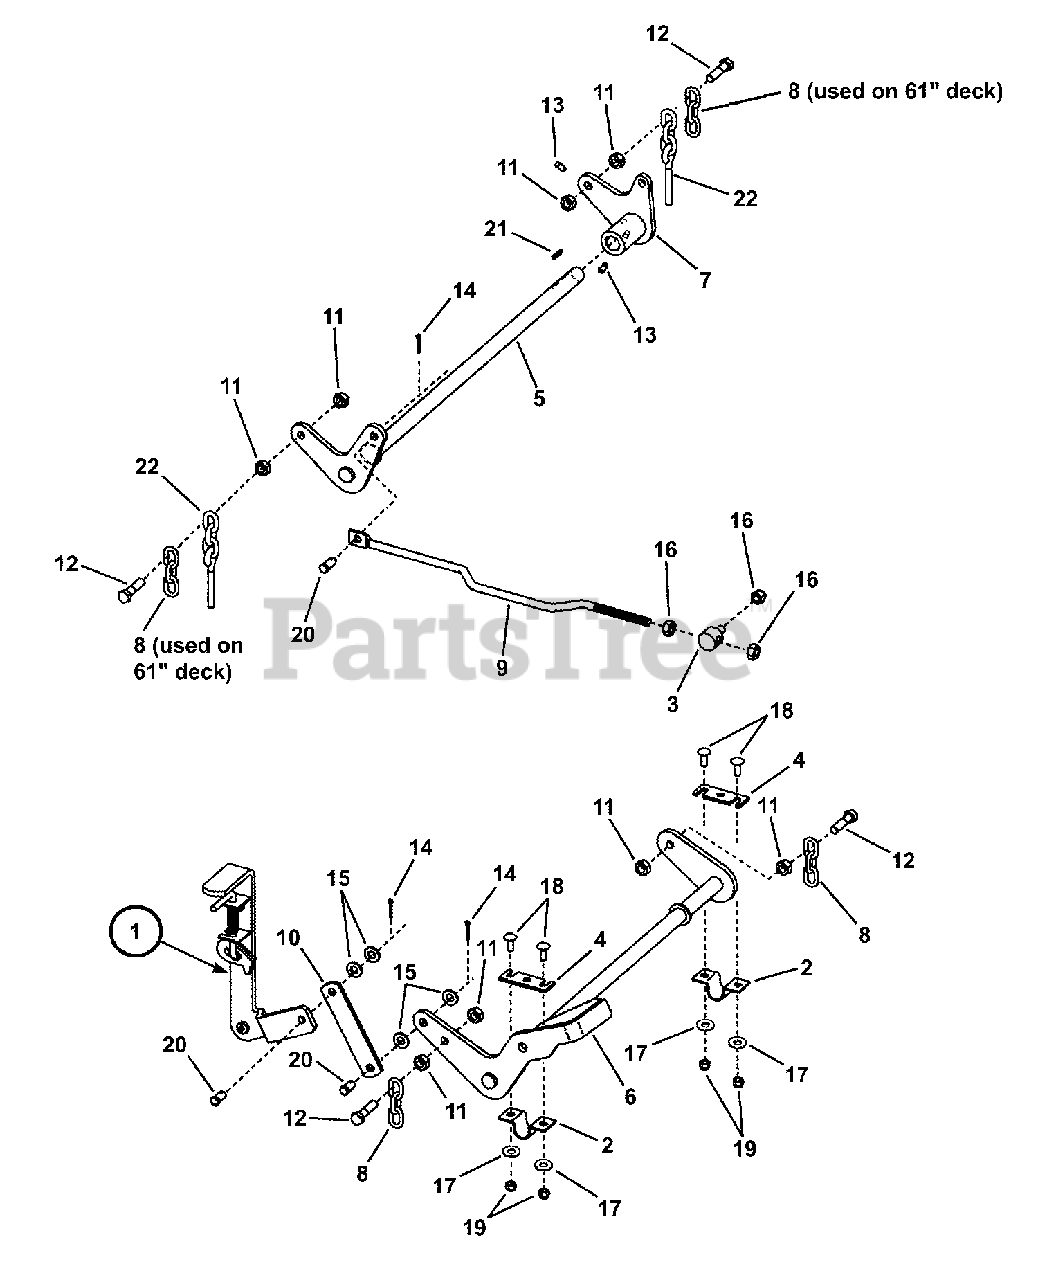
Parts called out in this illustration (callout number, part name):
1	ASSEMBLY, Deck Lift Handle
2	BRACKET, Deck Support
3	SWIVEL, Timing Rod (1/2-13 External Thread)
4	SHIM PLATE
5	WELDMENT, Rear Lift
6	WELDMENT, Front Deck Lift
7	WELDMENT, Bellcrank Lift
8	CHAIN, 3 Links
9	ROD, Timing (1/2-13 Thread)
10	LINK, Front
11	NUT, 1/2-13 Hex Flange Lock GR 5
12	SCREW, 1/2-13 x 2" Hex Head Cap, GR 5
13	SET SCREW, 5/16-18 Square Head Cup Point
14	PIN, 5/32 x 1" Cotter
15	WASHER, .531 I.D. Flat
16	NUT, 1/2-13 HEX SIDE LOCK
17	WASHER, 5/16" Flat
18	BOLT, 5/16-18 x 1" Short Neck Carriage, GR 5
19	NUT, 5/16-18 HEX NYLON LOCK
20	PIN, 1/2 x 1-1/8" Clevis
21	KEY, 3/16" Square x 1-1/2"
22	ASSEMBLY, Chain & Eyebolt
